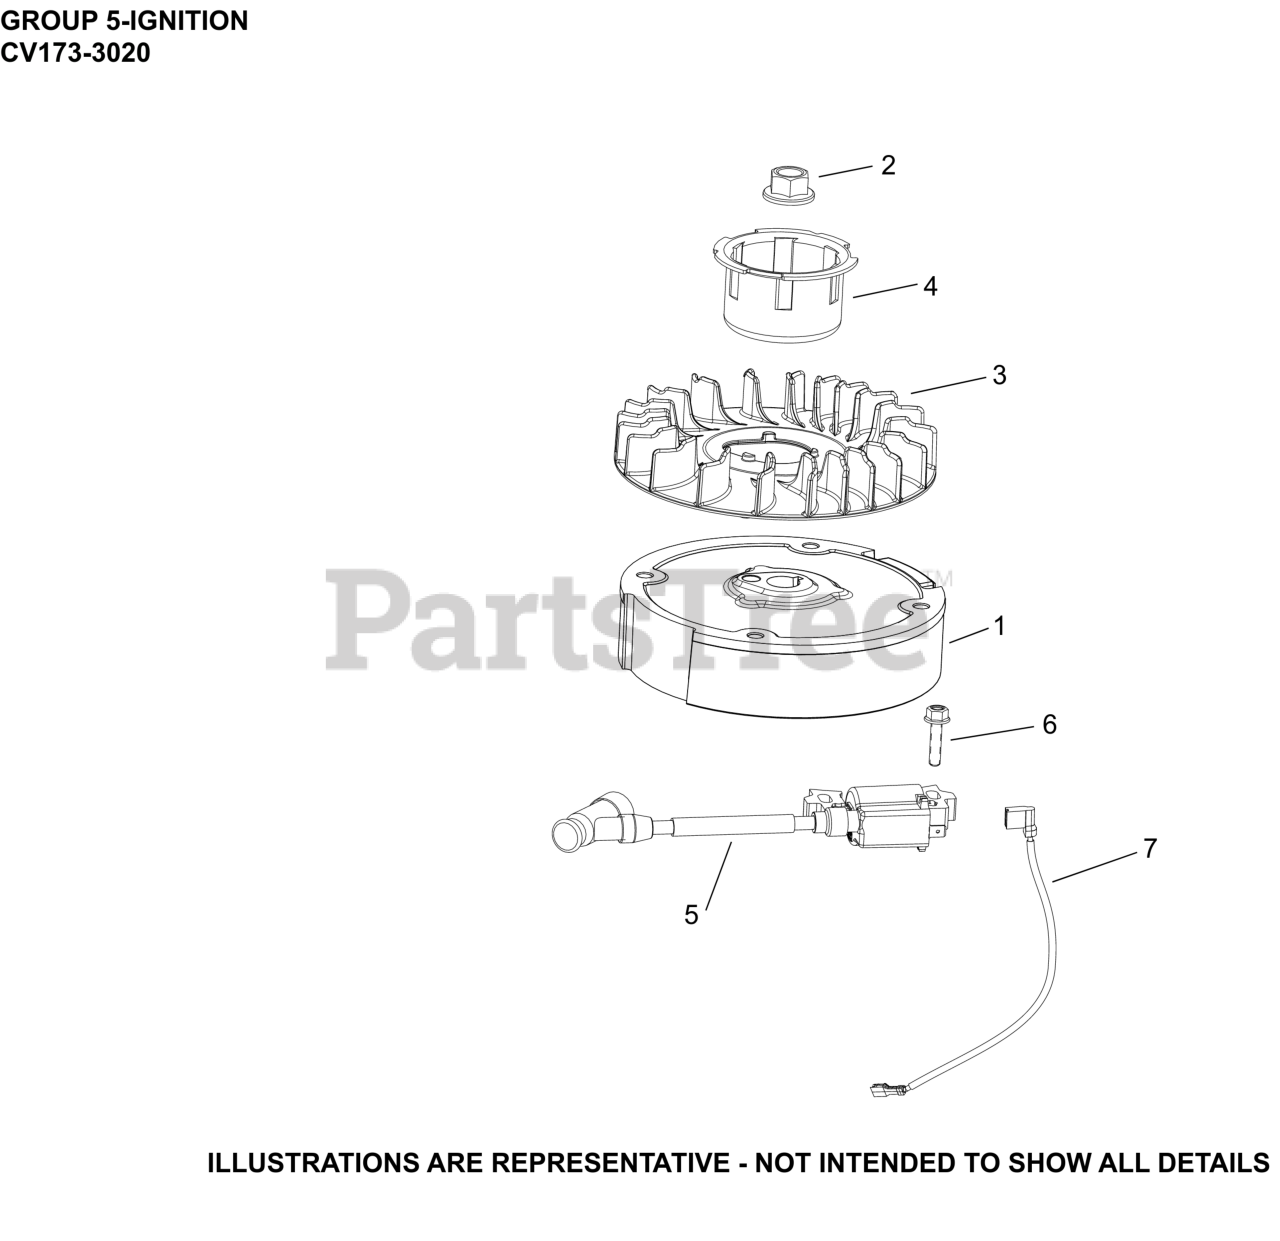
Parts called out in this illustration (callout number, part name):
1	FLYWHEEL (CAST IRON)
2	NUT, FLYWHEEL (W/SERRATIONS)
3	FAN, FLYWHEEL
4	CUP, STARTER DRIVE
5	MODULE IGN (#1458416S)
6	SCREW, M6 X 25-(#25086436S)
